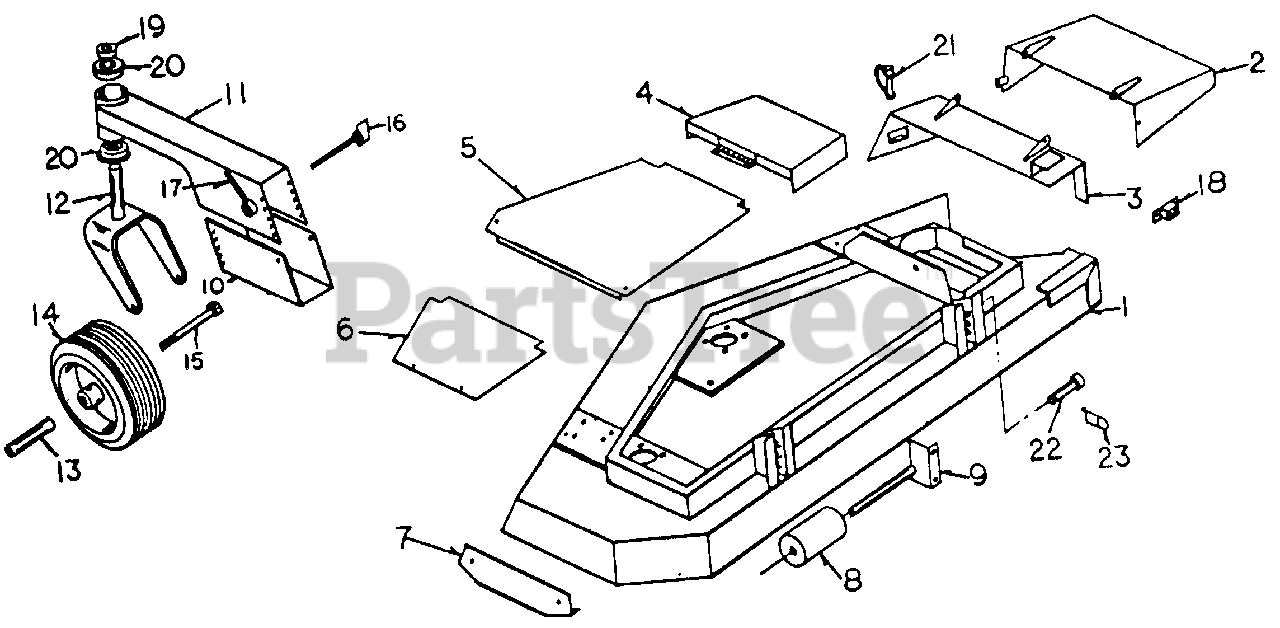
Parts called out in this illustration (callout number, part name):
3	Foot Guard Mount
8	Anti-scalp Roller
9	Shaft & Bracket
10	Gauge Wheel Mount Bracket
11	Gauge Wheel Mount
13	Axle
14	Gauge Wheel Assembly
18	10 Amp Circuit Breaker
19	Set Collar, 1"
23	Hair Pin Cotter
